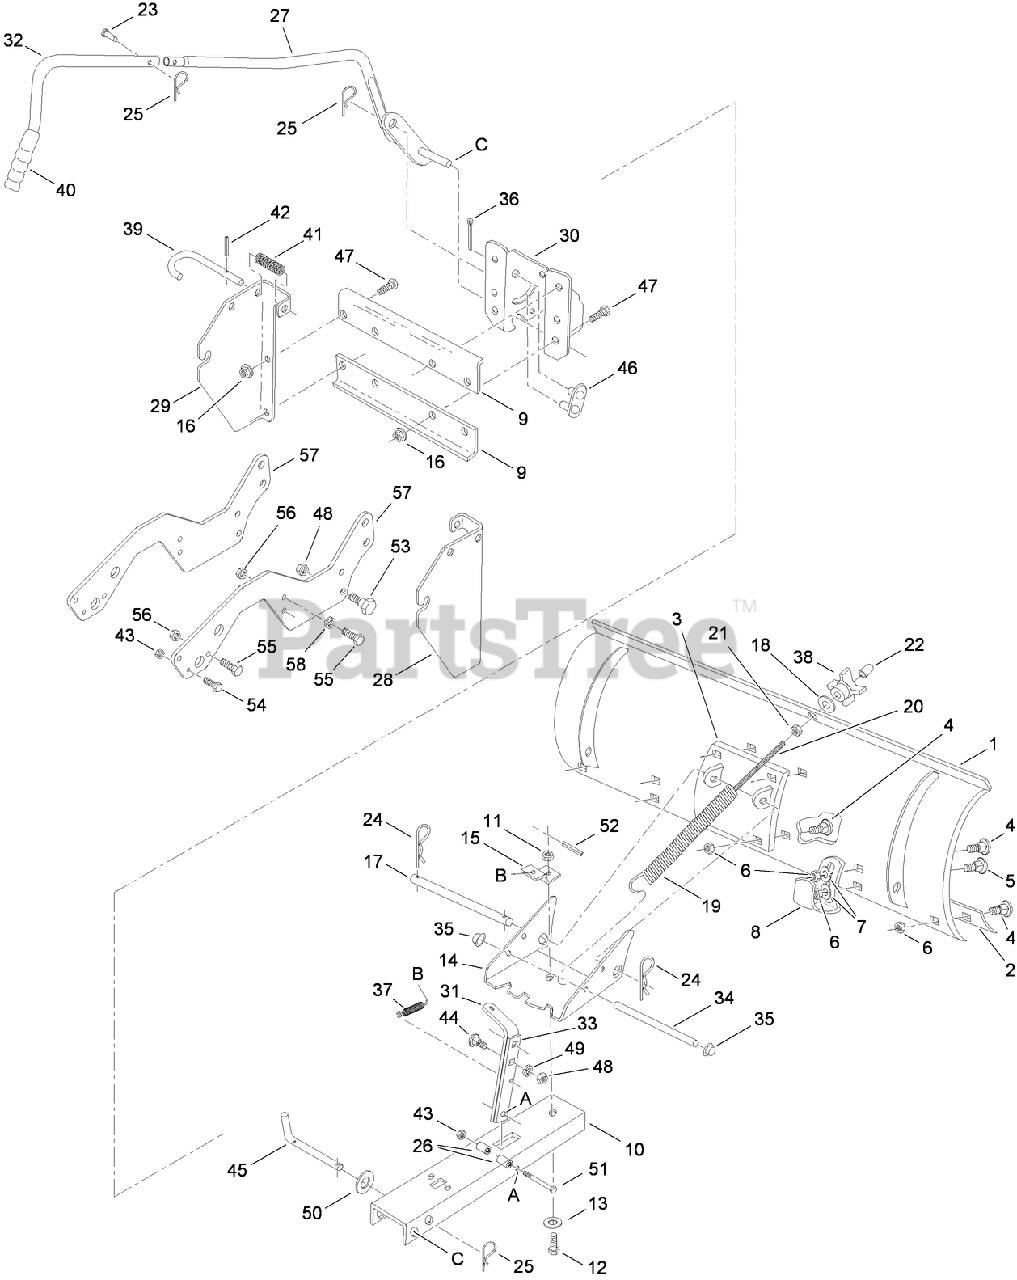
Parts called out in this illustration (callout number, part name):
2	PLATE-WEAR
3	REINFORCEMENT PLATE ASM
4	BOLT-CARR
5	BOLT-CARR
6	NUT-LOCK
7	WASHER
8	SKID-SHOE
9	BRACKET-SUPPORT, ANGLE
10	CHANNEL-PUSH
11	NUT-LOCK
12	BOLT-PIVOT, SPECIAL
13	WASHER-FLAT
14	PLATE-PIVOT
15	BRACKET-MOUNTING, SPRING
16	NUT-LOCK, FLANGED
17	SHAFT-PIVOT
18	WASHER-FLAT
19	SPRING-ADJUST, BLADE
20	SCREW-HH
21	NUT-HEX
22	CAP-PLASTIC
23	PIN-CLEVIS, LIFT HANDLE
24	PIN-HAIR
25	PIN-QUICK ATTACH
26	SPACER
27	LOWER LIFT HANDLE ASM
28	HITCH-BRACKET, RH
29	HITCH-BRACKET, LH
30	BRACKET-SUPPORT, PIVOT
31	BAR-LOCK, ANGLE (LONG)
32	HANDLE-LIFT, UPPER
33	BAR-LOCK, ANGLE (SHORT)
34	ROD-MOUNT, SPRING
35	NUT-PUSH
36	PIN-COTTER
37	SPRING-LOCK, ANGLE
39	PIN-ATACHMENT
40	GRIP-HANDLE
41	SPRING-COMPRESSION
42	PIN-SPRING
43	NUT-LOCK, FLANGE
44	BOLT-CARR
45	SHAFT-CHANNEL, PIVOT
46	LINK-LIFT
47	SCREW-HH
48	NUT-LOCK
49	WASHER-LOCK
50	WASHER
52	PIN-SPRING
53	BOLT-SHOULDER
54	SCREW-HH
55	SCREW-HH
56	NUT-NYLOCK
57	BRACKET-FRAME
58	WASHER-LOCK
